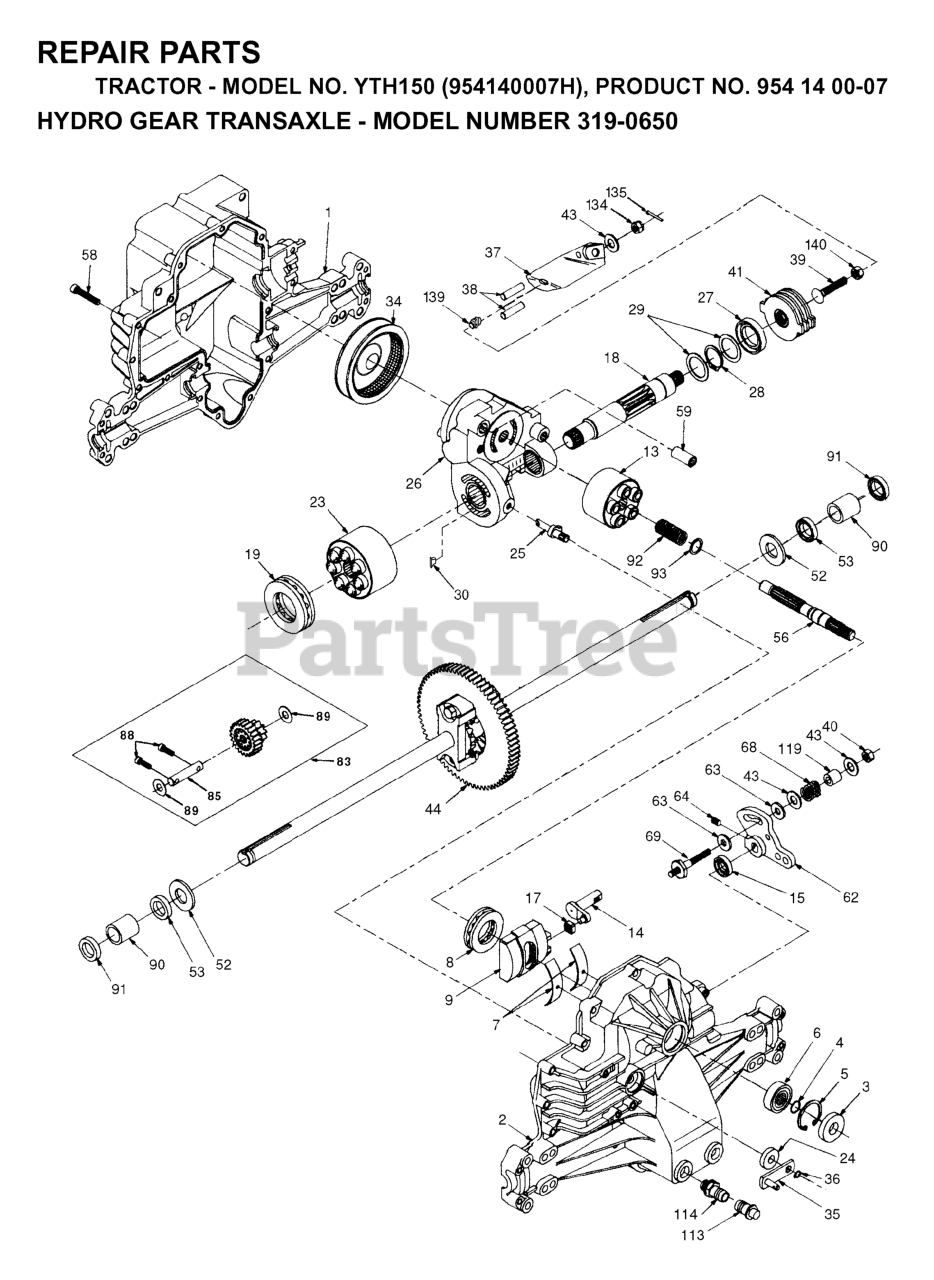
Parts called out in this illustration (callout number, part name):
3	Seal, Lip
8	Bearing, Thrust 30 x 52 x 13
13	Block, Cylinder Assembly
15	Seal, Lip
18	Shaft, Motor
19	Bearing, Thrust 42 x 68 x 16
23	Block, Cylinder Assembly
24	Seal, Lip 10 x 25 x 7
25	Actuator, Bypass
26	Center Section Assembly Kit
27	Seal, Lip 26 x 42 x 8
28	Ring, Retaining
29	Washer 26 x 35 x 1
34	Oil Filter Element
35	Arm, Bypass
36	Ring, Retaining
37	Arm, Actuating
38	Pin, Actuating
39	Bolt 5/16-24 x 1-3/4
40	Nut, Nylon Insert Hex Lock 5/16-24
41	Brake Rotor/Stator Kit
43	Washer 7/8 O.D. x 7/16 x .060
44	Differential Assembly
52	Washer 3/4 x 1.5 x .13
53	Seal .75 x 1.25 x .250
56	Shaft, Input
58	Bolt 1/4-20 x 1.38
59	Pin .5 OD x .43 ID x .750
62	Arm, Control
63	Puck, Dampener
64	Set Screw
68	Spring
69	Stud 5/16-24
83	Jack Shaft Assembly
91	Seal, Wiper
92	Spring, helical compression
93	Washer, Block Thrust
113	Cap, Vent Assembly
114	Fitting, O-Ring Assembly
119	Spacer
134	Nut, Castle 5/16-24
135	Pin, Cotter
139	Spring, Compression
140	Nut, Hex 5/16-24
